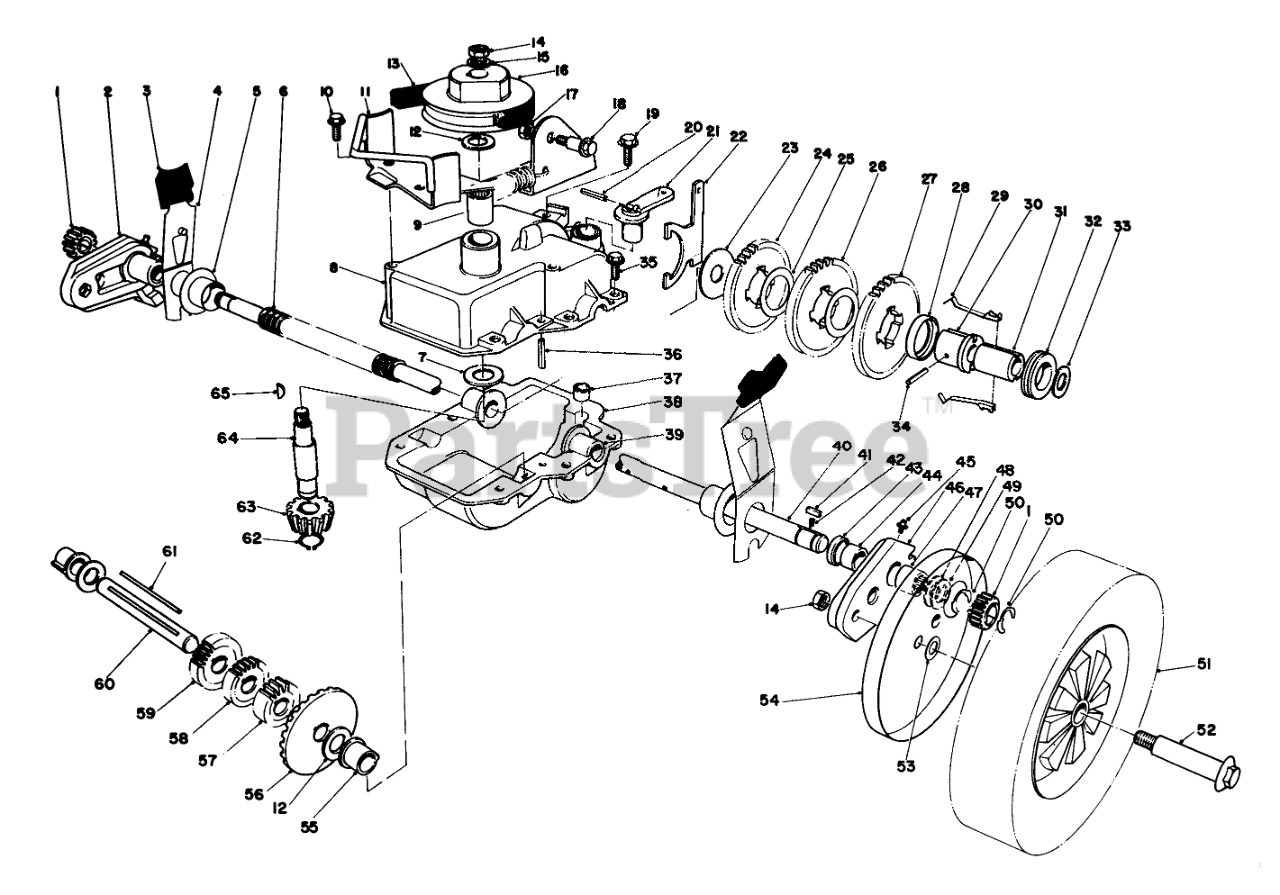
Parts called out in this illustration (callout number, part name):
1	GEAR-PINION
2	Pivot Arm R.H. (Incl. Ref. #43-45 & 47)
3	KNOB-ARM
4	SPRING ARM ASM SP
5	CAP-END
6	CONDUIT-CONVOLUTED, SPLIT
7	Thrust Washer
8	Case-Upper
9	Bearing
10	SCREW
11	Belt Guide Bracket
12	WASHER-THRUST
13	V-BELT
14	Nut
15	WASHER-FLAT
16	PULLEY
17	NUT-LOCK, CONE
18	SHOULDER BOLT
19	SCREW-HWHTF
20	PIN-COIL
21	LEVER-SHIFT
22	Shift Yoke
23	WASHER
24	GEAR-38T
25	WASHER
26	Gear-40 Tooth
27	GEAR-42T
28	KEY RETAINER
29	Key
30	Body-Sleeve
31	SLEEVE
32	COLLAR-SHIFT
33	WASHER-PLAIN
34	PIN-SPRING
35	SCREW-HWH, THREAD ROLL
36	ROLL PIN 3/16 X 1 IN
37	BUSHING-YOKE
38	LOWER GEAR CASE CAST
39	Bushing
40	Output Shaft
41	KEY RECTANGULAR
42	SPRING-COMPRESSION
43	Seal
44	Bushing
45	FITTING-GREASE
46	Pivot Arm L.H. (Incl. Ref. #43-45 & 47)
47	Needle Baring
48	Washer
49	THRUST WASHER
50	RING-RETAINING
51	Wheel & Tire Assy.
52	BOLT-WHEEL
53	WASHER
54	WHEEL COVER
55	Botching Shaft
56	BEVEL GEAR
57	14 T GEAR
58	16 T GEAR
59	GEAR-18T
60	Sort Shaft
61	Key Square
62	RING-RETAINING
63	DECAL - INSTRUCTION
64	INPUT SHAFT
65	KEY-WOODRUFF
